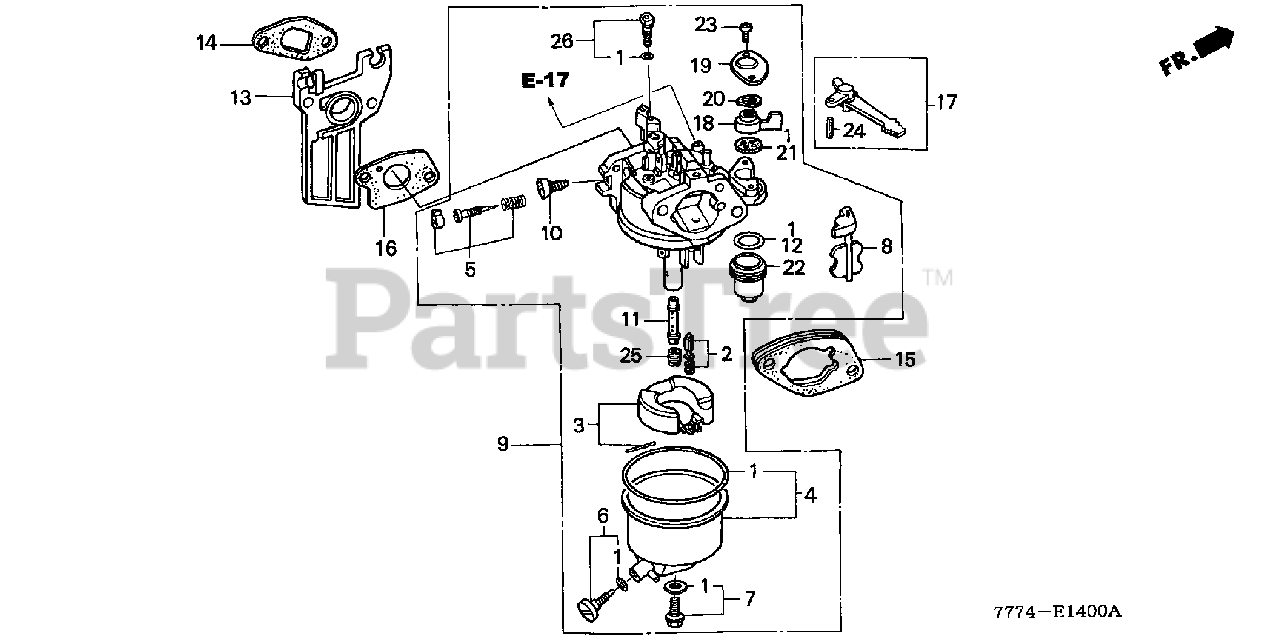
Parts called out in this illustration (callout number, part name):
1	GASKET SET
2	VALVE SET, FLOAT
4	CHAMBER SET, FLOAT
5	SCREW SET, PILOT
6	SCREW SET, DRAIN
7	SCREW SET
9	CARBURETOR ASSY. (BE64L B)
10	SCREW, THROTTLE STOP
11	NOZZLE, MAIN
12	GASKET, FUEL STRAINER CUP
13	INSULATOR, CARBURETOR
14	GASKET, INSULATOR
15	SPACER, CARBURETOR
16	GASKET, CARBURETOR
17	LEVER, CHOKE (STD)
18	LEVER, PETCOCK
19	PLATE, LEVER SETTING
20	SPRING, PETCOCK LEVER
21	GASKET, PETCOCK
22	CUP, FUEL STRAINER
23	SCREW, PAN (3X6)
24	PIN, SPRING (2X12)
25	JET, MAIN (#68)
25	JET, MAIN (#70)
25	JET, MAIN (#72)
26	JET SET, PILOT (#45)
